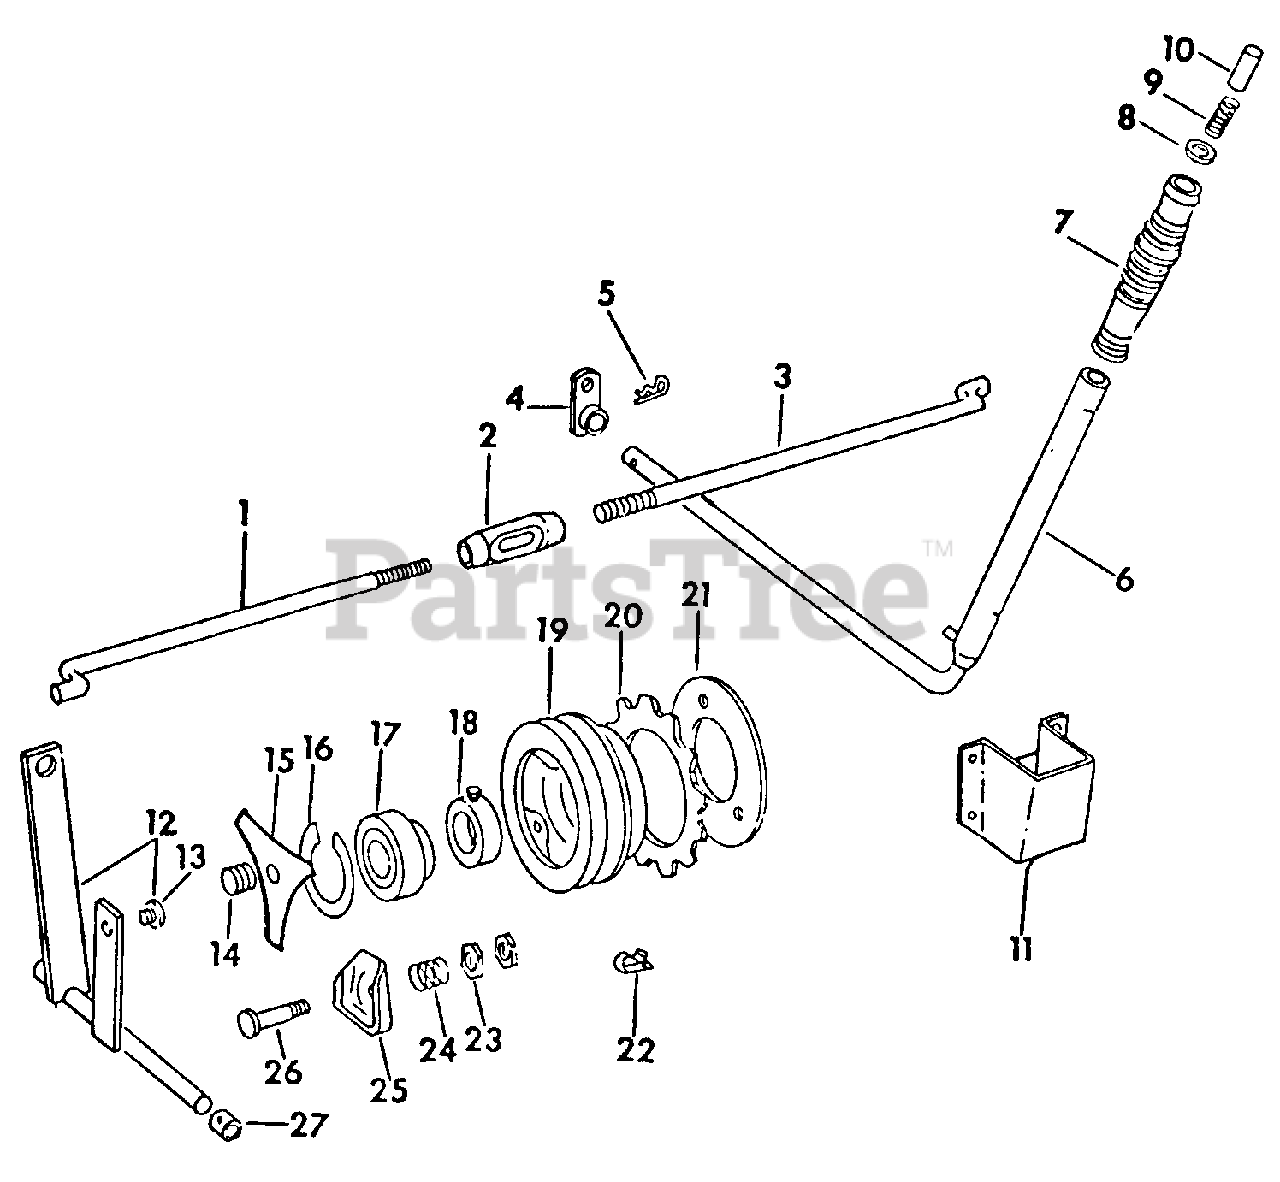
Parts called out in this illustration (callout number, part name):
2	Turnbuckle, Rod
3	Rod, Rear Clutch
4	Lever Assy, Pivot
5	Pin, Quick Attachable Cotter
6	Handle Assy, PTO
8	Retainer, Release Rod Spring
9	Spring
10	Pin, Handle Release Rod
11	Bracket Assy, PTO Handle
12	Rockshaft Assy, PTO Clutch
13	Button, Wear
14	Button, Thrust
15	Spring, Pressure
16	Ring, Snap 2.197 O.D., for Pulley
17	Bearing, Ball
18	Collar w/Set Screw & Lock Nut, Bearing
19	Pulley, Mower Actuating
20	Disc, Friction
21	Plate, Pressure
22	Spring, Disc
23	Nut, 1/4-28 Hex Jam
24	Spring, Compression
25	Lever, Throw-Out
26	Screw, Special Machine
27	Bushing, Rockshaft
